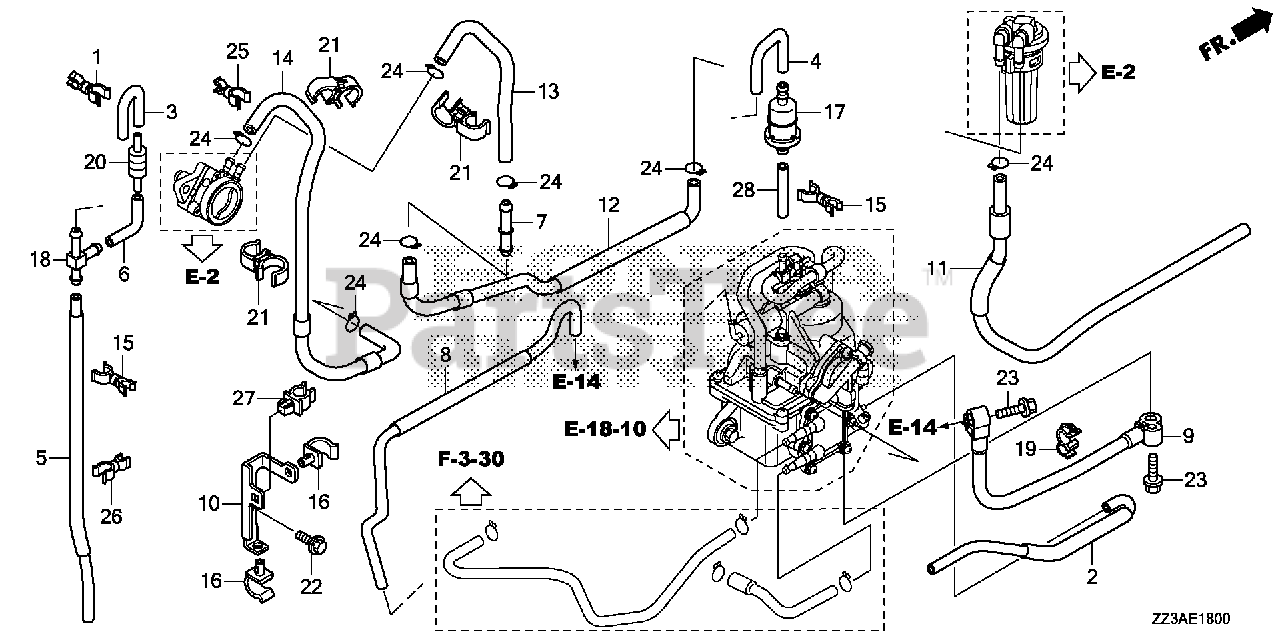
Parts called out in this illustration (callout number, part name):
1	CLAMP, OIL HOSE
2	TUBE, DRAIN
3	TUBE B, CHECK VALVE
4	TUBE C, AIR VENT
5	TUBE D, AIR VENT
6	TUBE E, AIR VENT
7	JOINT, FUEL FEED HOSE
8	TUBE, PRESSURE REGULATOR CONTROL
9	HOSE, FUEL
10	BRACKET, TUBE CLAMP
11	TUBE A, FUEL
12	TUBE B, FUEL
13	TUBE D, FUEL
14	TUBE C, FUEL
15	CLAMP, AIR VENT TUBE
16	CLAMP B, FUEL TUBE
17	FILTER, FUEL
18	JOINT, THREE WAY
19	CLAMP, TUBE (7.5-11.5) (BLACK)
20	VALVE, CHECK
21	CLIP, SENSOR HOSE
22	BOLT, FLANGE (6X14) (CT200)
23	BOLT, FLANGE (6X25)
24	CLIP, TUBE (B12)
25	CLAMP (6MM-12MM)
26	CLIP, WIRE
27	CLIP, TUBE (3.5)
28	BULK HOSE, FUEL (5.5X3000) (5.3X35)
